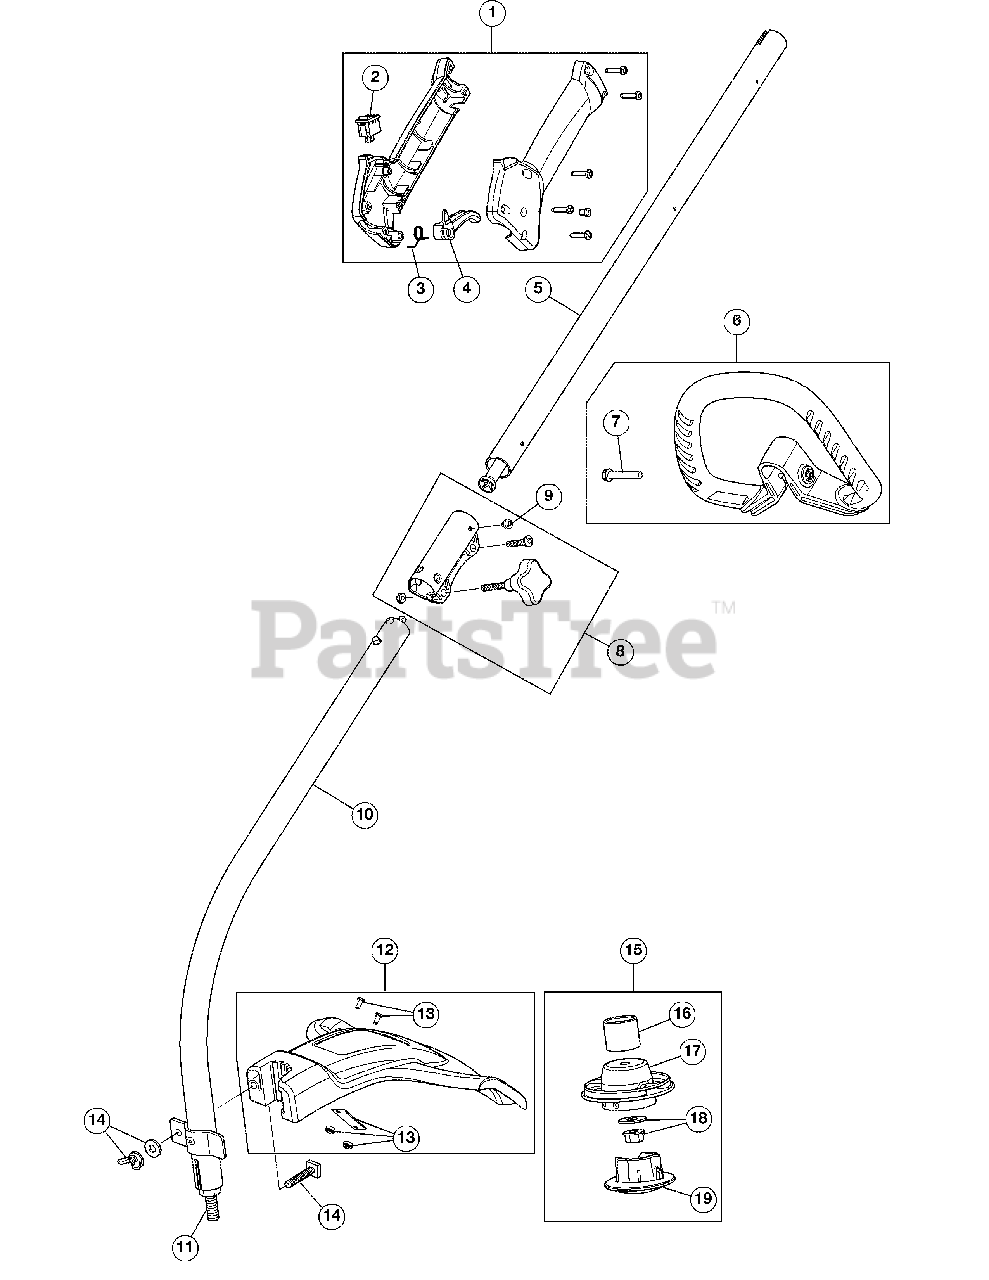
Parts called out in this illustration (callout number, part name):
1	Throttle Housing Assembly (Incl. 2 - 4)
2	Switch Assembly
3	Throttle Trigger Spring
4	Throttle Trigger
5	Upper Shaft Housing Assembly
6	Deluxe D-Handle Assembly (Incl. 7)
8	Split Boom Coupler (Incl. 9)
9	Coupler Anti-Rotation Screw
10	Lower Drive Shaft Housing Assembly (Incl. 11)
11	Lower Flexible Drive Shaft
12	Shield Assembly (Incl. 13)
13	Blade Assembly
14	Shield Mounting Hardware
15	Cutting Head Assembly
16	Weed Guard
17	Cutting Head Spool
18	Spool Mounting Hardware
19	Cutting Head Cap
